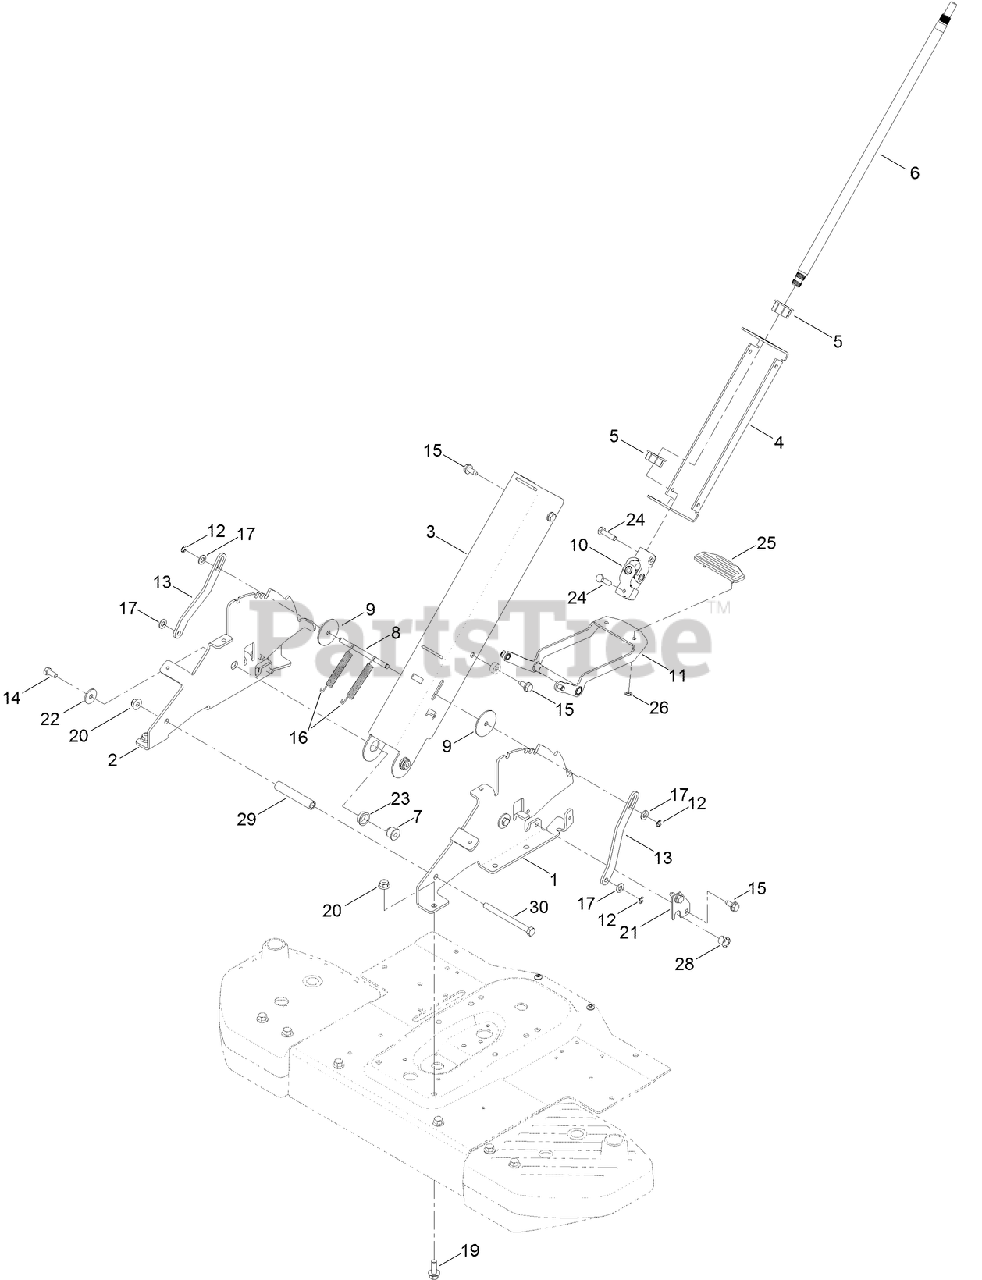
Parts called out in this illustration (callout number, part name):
1	BRACKET-PIVOT, COLUMN (LH)
2	BRACKET-PIVOT, COLUMN (RH)
3	COLUMN-FRONT
4	COLUMN-BACK
5	BUSHING-STEERING, UPPER
6	SHAFT-STEERING, UPPER
7	SPACER-PIVOT, COLUMN
8	ROD-PLUNGER
9	WASHER-SHAFT, TILT
10	U-JOINT ASM
11	RELEASE PEDAL ASM
12	E-RING
13	PLATE-PLUNGER
14	SCREW-HH
15	SCREW-HWHTF
16	SPRING-EXTENSION
17	WASHER-PLAIN
19	SCREW-HHF
20	NUT-HF, NI
21	PLATE-RETAINER
22	WASHER-PIVOT
23	BUSHING-FLANGE
24	SCREW-HH
25	PAD-TILT PEDAL
26	NUT-PUSH
28	BUSHING-NYLINER
29	SPACER
30	SCREW-HH
